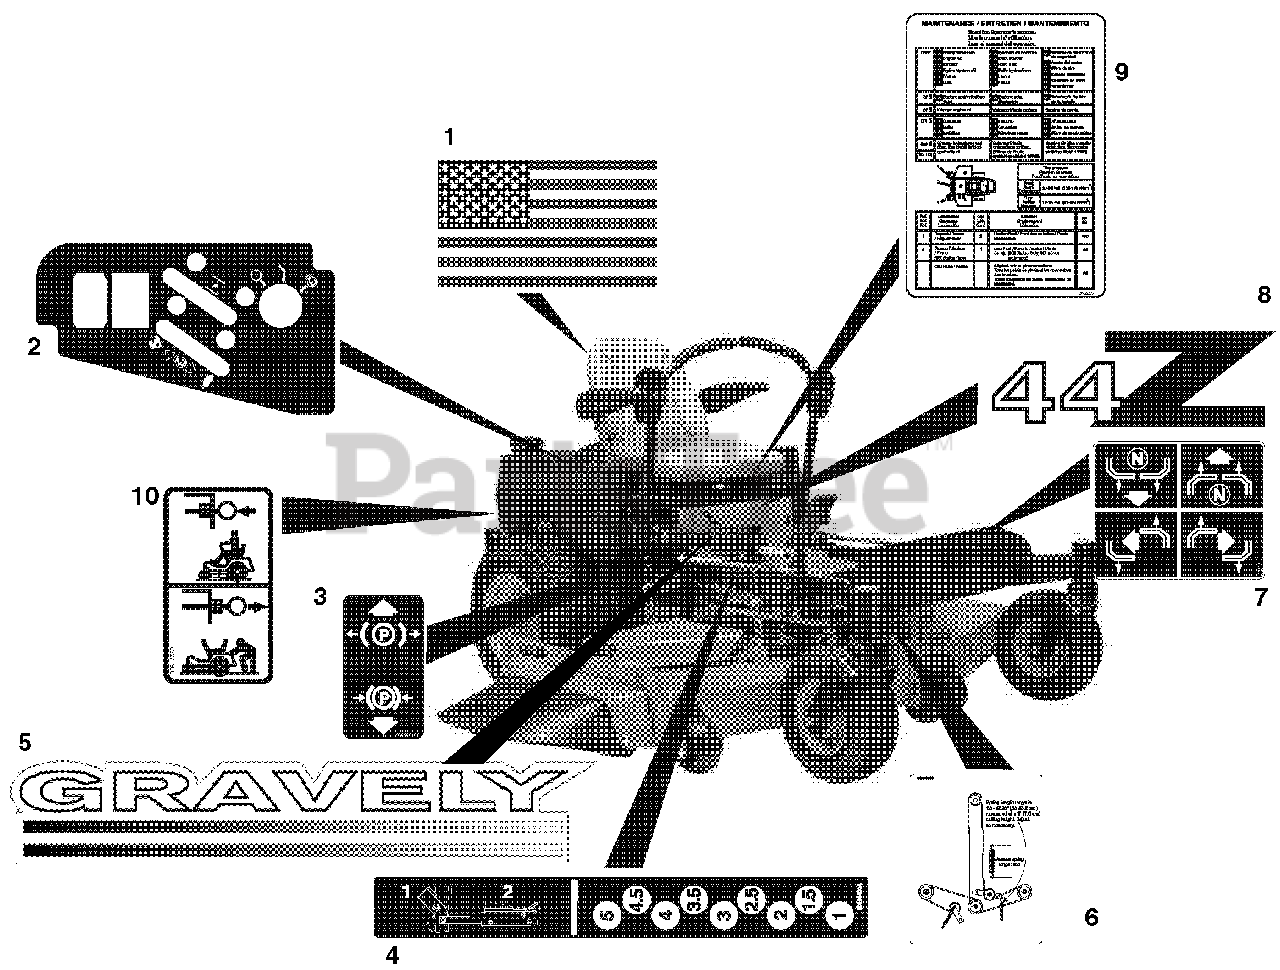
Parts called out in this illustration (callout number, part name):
1	Decal, American Flag
2	Decal, Control Panel
3	Decal, Parking Brake Lever
4	Decal, Height of Cut
5	Decal, ZT Hood
6	Decal, Belt Diagram
7	Decal, Instructional Steering
8	Decal, PM 44Z
8	Decal, Gravely 48Z
9	Decal, Maintenance Instructions
10	Decal, Transmission Disconnect
